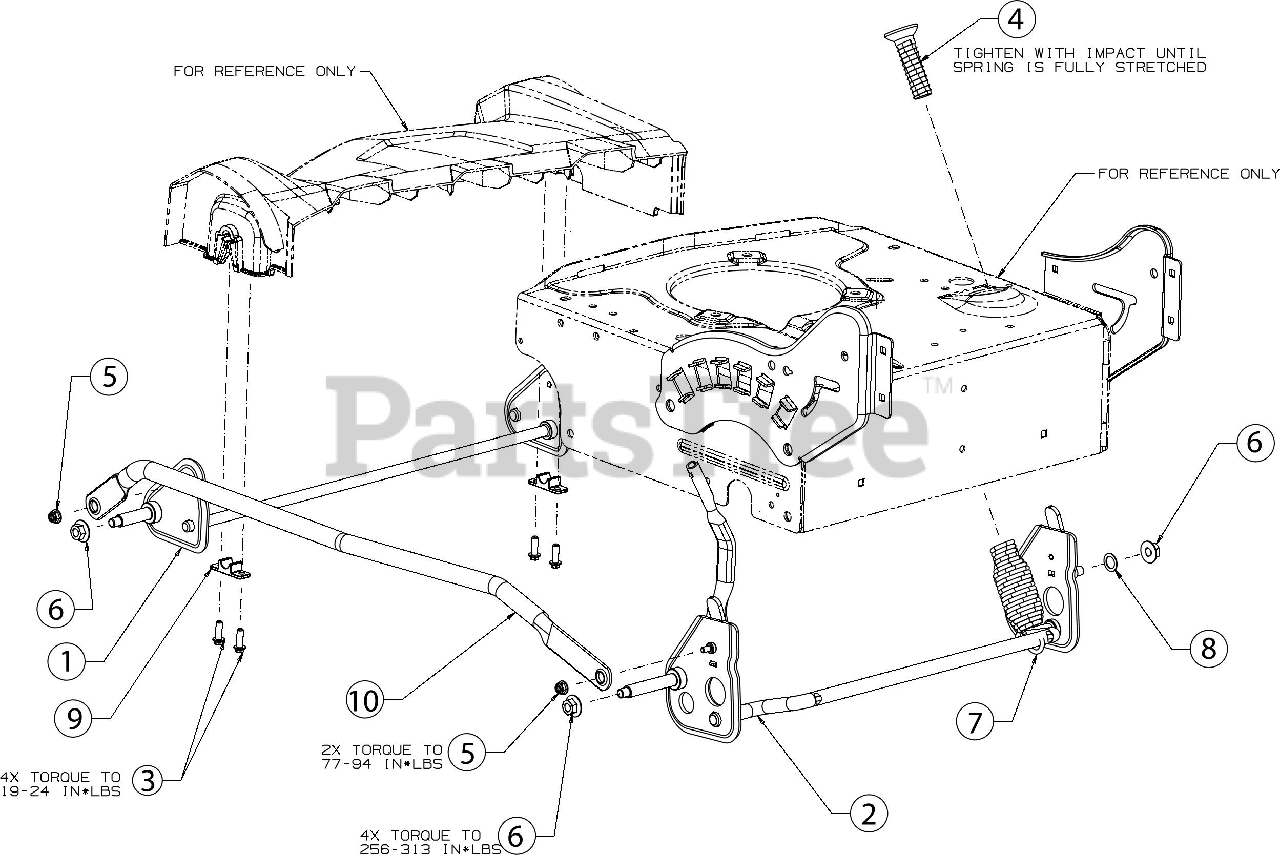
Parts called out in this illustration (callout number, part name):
1	FRONT AXLE ASSEMBLY
2	REAR AXLE ASSEMBLY
3	SCREW 1/4 x .750
4	LIFT SPRING INSERT
5	FLANGE LOCK NUT
6	FLANGE LOCK NUT
7	EXTENTION SPRING
8	WASHER .510 x .750 x .033
9	BLOCK BUSHING
